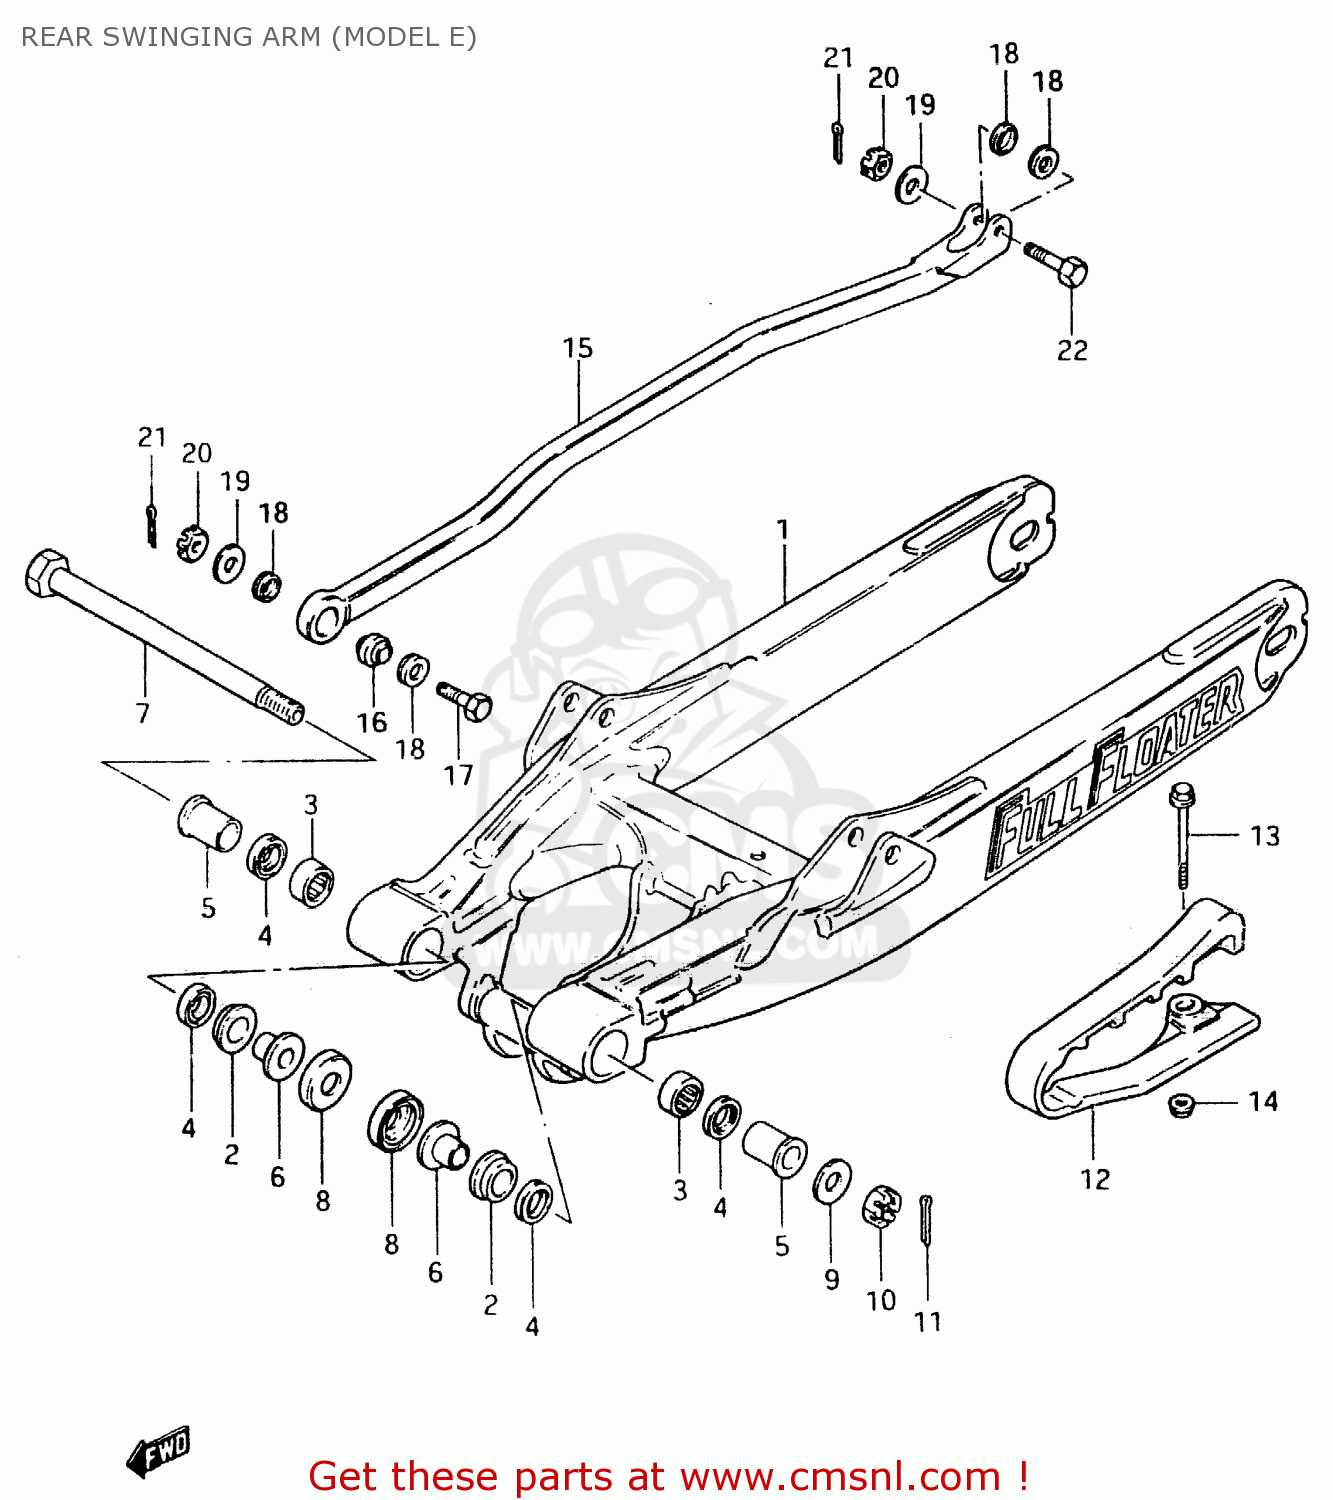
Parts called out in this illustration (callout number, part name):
1	SWING ARM ASSEMBLY,REAR
2	BUSHING,REAR SWING ARM PIVOT
3	BEARING(20X27X20)
4	OIL SEAL
5	SPACER,RR SWGARM PIVOT
6	SPACER,RR SWGARM PIVOT INNER
7	SHAFT,RR SWINGINGARM PIVOT
8	COVER,RR SWGARM DUST SEAL
9	WASHER(14.5X29X2.3)
10	NUT
11	COTTER PIN
12	BUFFER,CHAIN TOUCH DEFLECTOR
13	BOLT 6X65
14	NUT
15	LINK,REAR TORQUE
16	SPHERICAL BEARING,TORQUE
17	BOLT 8X28
18	19
19	WASHER
20	NUT 8MM
21	PIN 20X20
22	BOLT 8X29.5
